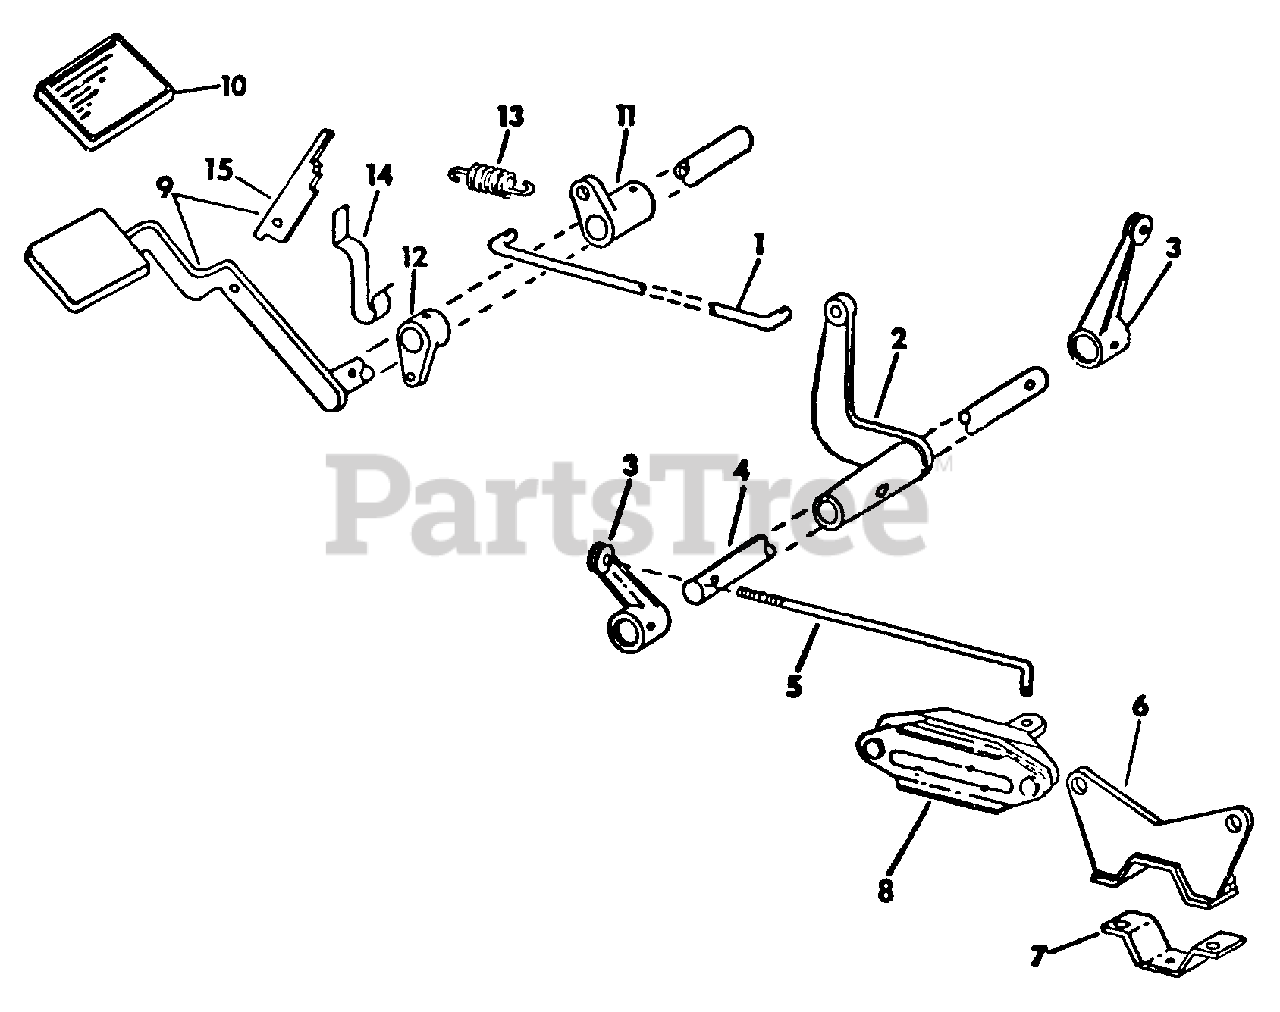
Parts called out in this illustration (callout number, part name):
2	Lever, Brake
4	Shaft, Brake Pivot
6	Bracket Assy, Caliper
7	Flange, Caliper Mounting
7	Screw, 3/8-16 X 1-1/4 Cdp Hex Hd
8	Caliper Assy, Brake
9	Pedal Assy, Clutch
10	Pad, Pedal
11	Lever, Brake Rod
12	Lever, Neutral Return
13	Spring, Brake Pedal Return
14	Spring, Safety Switch Operating
